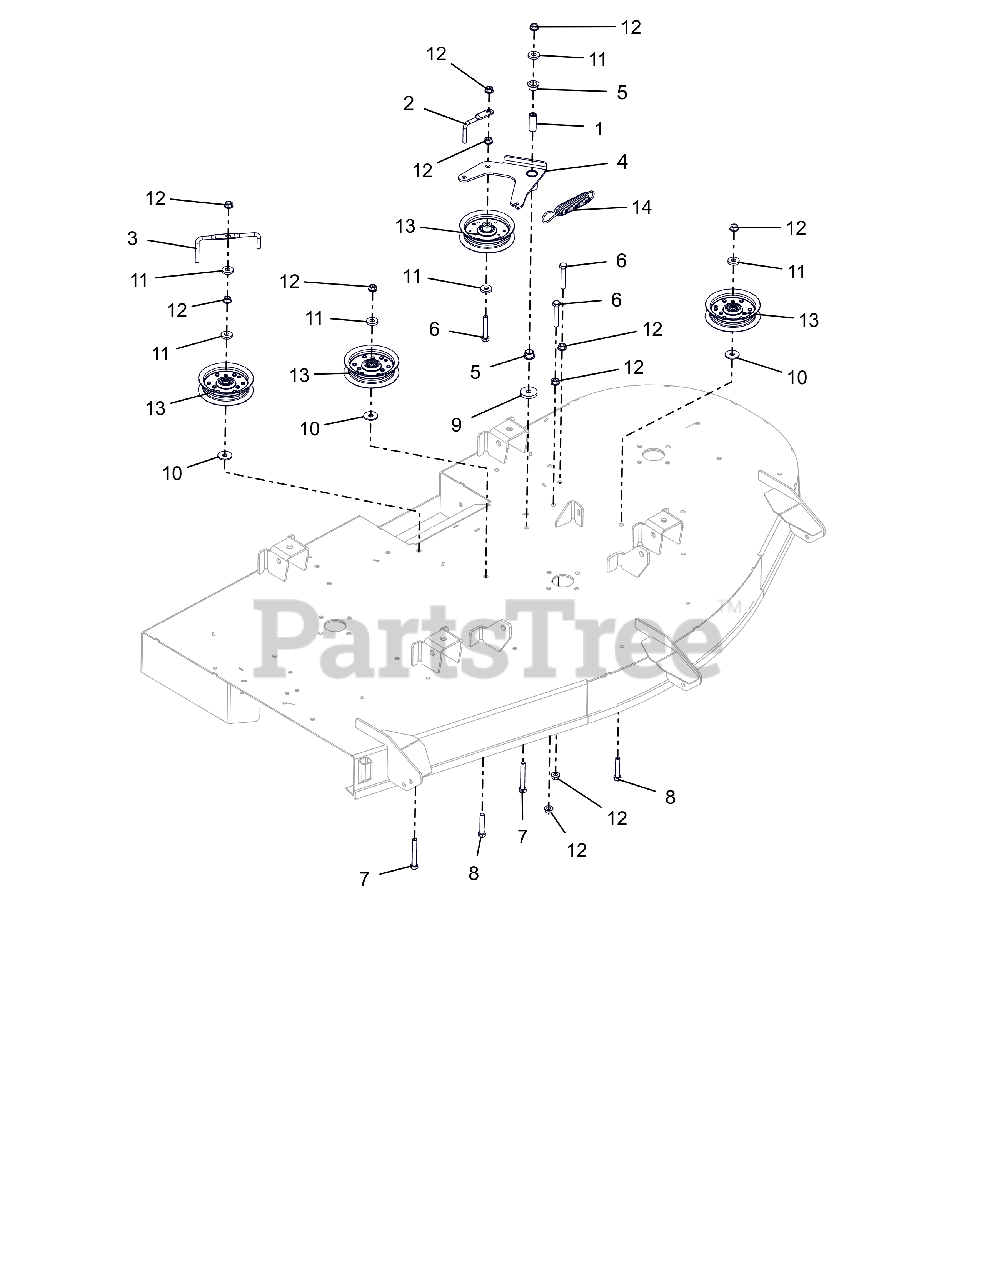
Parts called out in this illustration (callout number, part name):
1	SPACER, .375IDX.625ODX1.66 PM
2	WIREFORM, BELT FINGER
3	WIREFORM, BELT FINGER
4	WLDMT, IDLER ARM-42"
5	BSHG-FLG, .625X.750X.500X1.00
6	BLT,HEX .38-16X2.25 G5 ZCC
7	BLT, HEX .38-16X2.75 G5 ZCC
8	BLT,HEX .38-16X2.00 G5 ZCC
9	WSHR, FLT .406X1.50X.245 ZCC
10	WSHR FL STL .406X1.25X.10ZC120
11	WSHR, FLT .406X1.00X.188 ZCC
12	NUT-LK-TOP-FLG .38-16 ZC120
13	ASM, IDLER 4"
14	SG-TENS .135X.98X6.0 WLD 62
